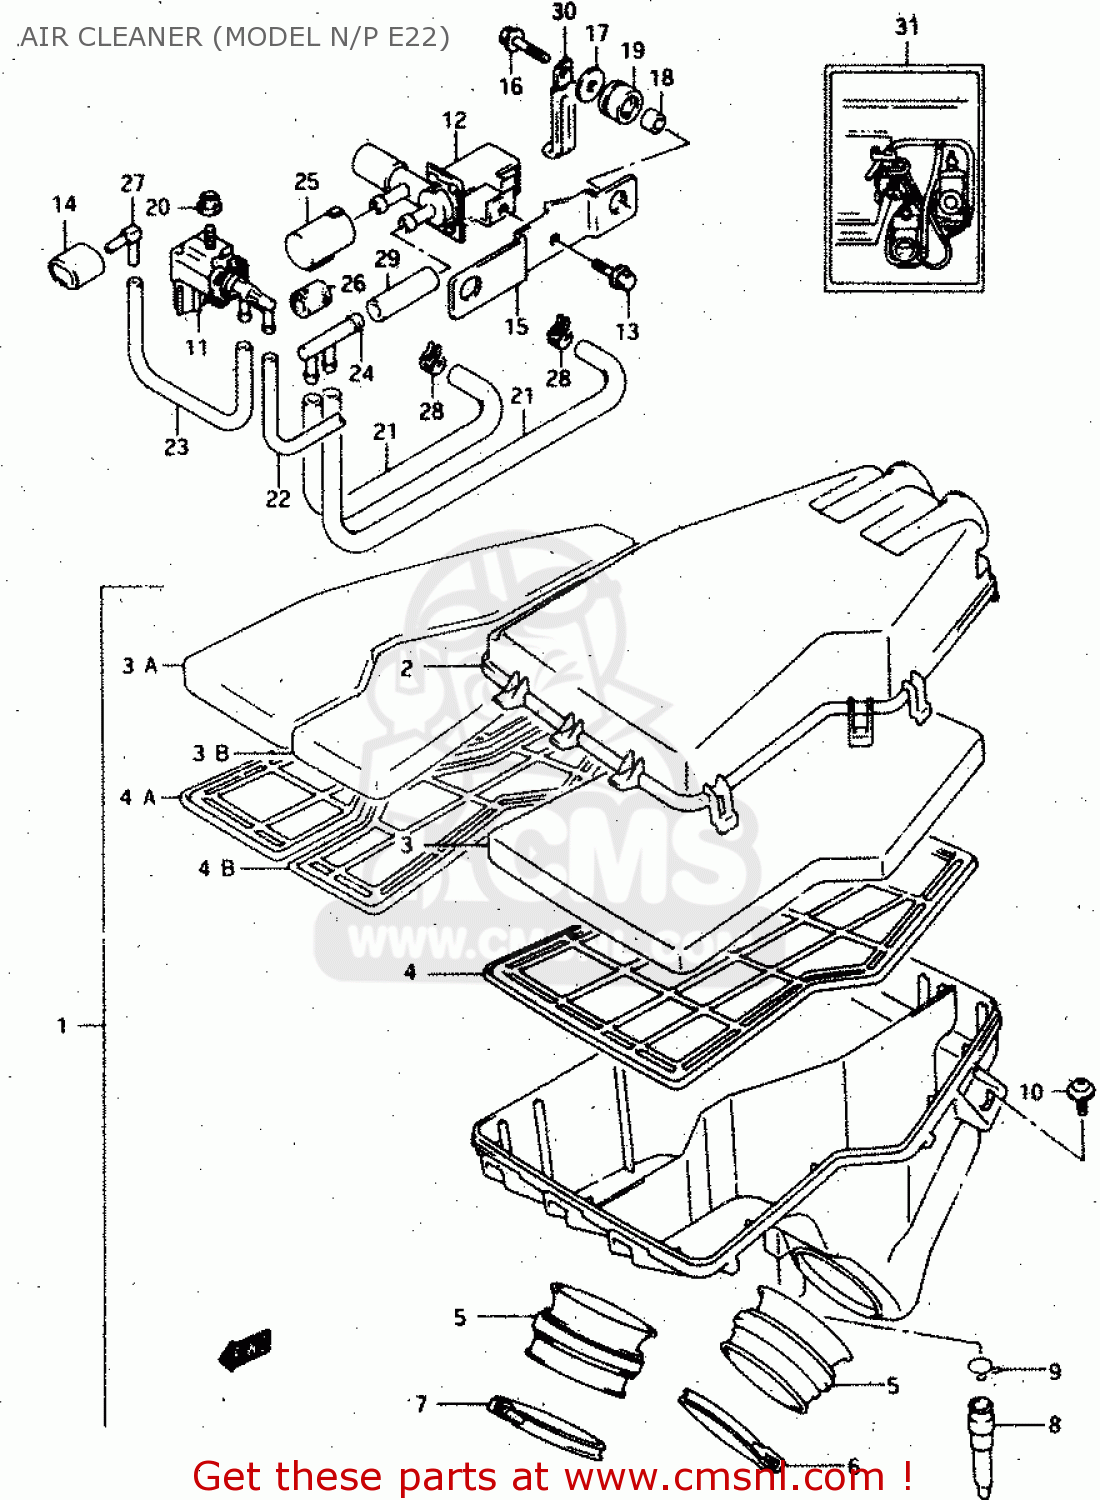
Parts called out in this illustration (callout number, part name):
1	CLEANER ASSY, AIR
2	CAP,AIR CLEANE
3	FILTER
3A	FILTER,AIR,R
3B	FILTER,AIR,L
4	HOLDER,FILTER
4A	HOLDER,FILTER,R
4B	HOLDER,FILTER,L
5	TUBE,OUTLET
6	CLAMP
7	CLAMP
8	DRAIN TUBE
9	CLIP
10	SCREW(6X16)
11	VALVE ASSY,MAIN AIR SOLENOID
12	VSV,IDLE UP
13	BOLT
14	FILTER,SOLENOID VALVE
15	BRACKET, SOLENOID VALVE
16	BOLT 6X20
17	WASHER
18	SPACER(9.2X9X6.5)
19	CUSHION
20	NUT
21	HOSE,VACUUM
22	HOSE(4X7X600)
23	HOSE(4X7X600)
24	SEPARATOR
25	CASE, FILTER
26	FILTER
27	UNION
28	CLAMP
29	HOSE (7X12X300)
30	CLAMP
31	LABEL, CARBURETOR WARNING
